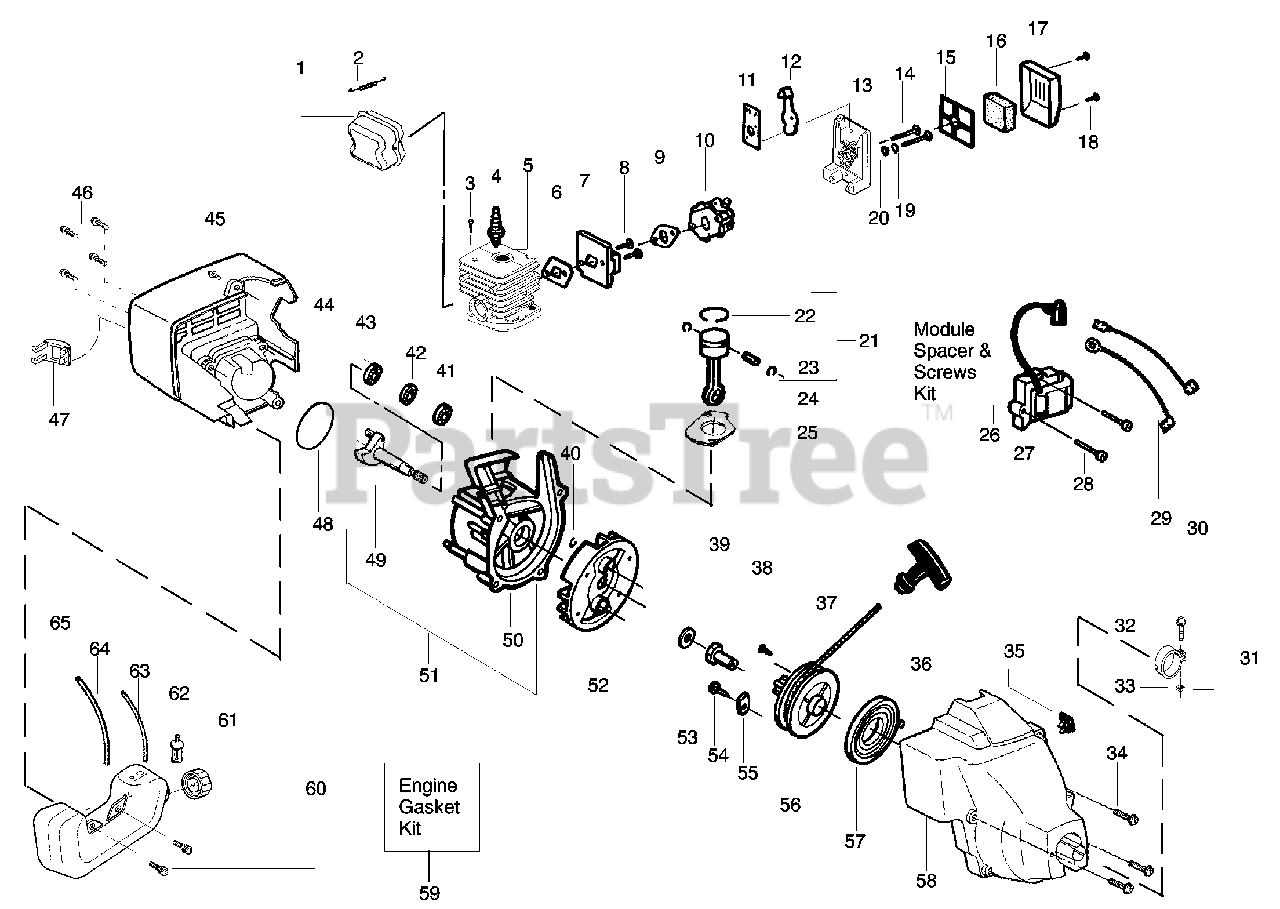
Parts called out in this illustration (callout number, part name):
1	Kit - Muffler
2	Spring-Muffler
3	Screw-Cylinder
4	Spark Plug (RCJ 6Y)
5	Kit - Cylinder
6	Gasket-Cyl/Carb.(kit)
7	Adapter-Carb.
9	Gasket-Carb.(kit)
10	Kit - Carburetor Ass'y (WT-631)
11	Plate-Choke Mounting
12	Shutter-Choke
15	Plate - Filter Support
16	Foam-Air Filter
17	Cover-Air Filter
19	Spacer-Choke
21	Kit - Piston
22	Ring-Piston
23	Retainer-Piston Pin
24	Assy-Connecting Rod
25	Gasket-Cylinder (kit)
26	Kit-Module Spacer & Screws
27	Module-Ignition
29	Assy-Ground Wire
30	Assy-Leadwire
31	Assy-Nose Cone Clamp
32	Screw-Nose Cone
33	Nut-Nose Cone
34	Screw
35	Kit-Momentary Switch
36	Handle-Starter
37	Kit - Rope
39	Coupling-Drive
40	Retain. Ring-C'shaft
41	Bearing-Outer
42	Kit-C'case Seal
43	Bearing-Inner
44	Shroud-Rear
46	Screw
47	Guard-Muffler
48	O-Ring-C'case (kit)
49	Assy-Crankshaft
50	Kit-Assy-Crankcase
51	Kit-Assy-C'case & Crankshaft
52	Assy-Flywheel
53	Washer-Flat
55	Retainer
56	Kit-Starter Pulley
57	Spring-Starter
58	KIT-Fan Hsg. Assy.
59	Kit-Engine Gasket
60	Retainer-Fuel Tank
61	Assy-Fuel Cap w/ret.
62	Assy-Fuel Pickup
63	Kit-Fuel Line (Small)
64	Kit-Fuel Line (Large)
65	Assy-Fuel Tank
